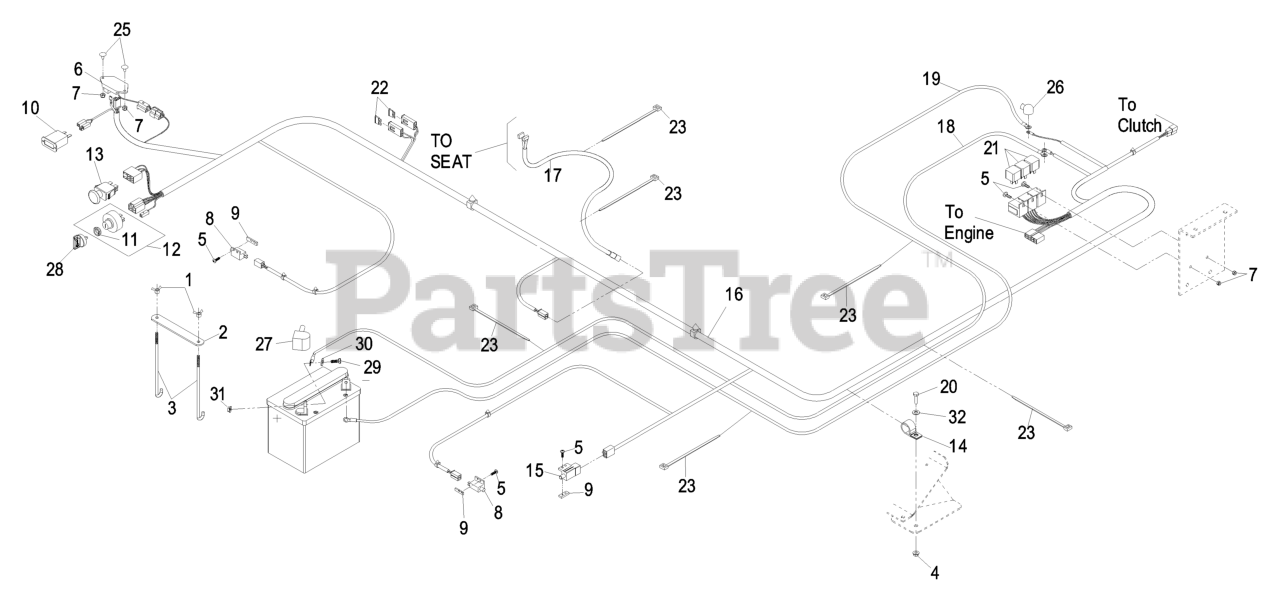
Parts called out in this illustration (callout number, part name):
1	WINGNUT
2	STRAP-HOLDDOWN, BATTERY
3	BOLT-HOLDDOWN
5	SCREW-PPH
6	MODULE-DELAY, SEAT
7	NUT-LOCK, NI
8	SWITCH-OPEN, NORMALLY
9	PLATE-TAPPED
10	METER-HOUR
11	NUT-SWITCH, IGNITION
12	ASM,SWITCH W/NUT
13	SWITCH-PTO
14	CLIP-LOOM
16	HARNESS,WIRE LXS AC
17	HARNESS-WIRING, SEAT
18	WIRE-GROUND
20	SCREW-HH
22	FUSE-BLADE TYPE, 20 AMP
23	TIE-PLASTIC
25	BOLT-CARR
26	INSULATOR-SOLENOID
28	KEY-IGNITION
29	SCREW-HH
30	WASHER-FLAT
32	WASHER-PLAIN
